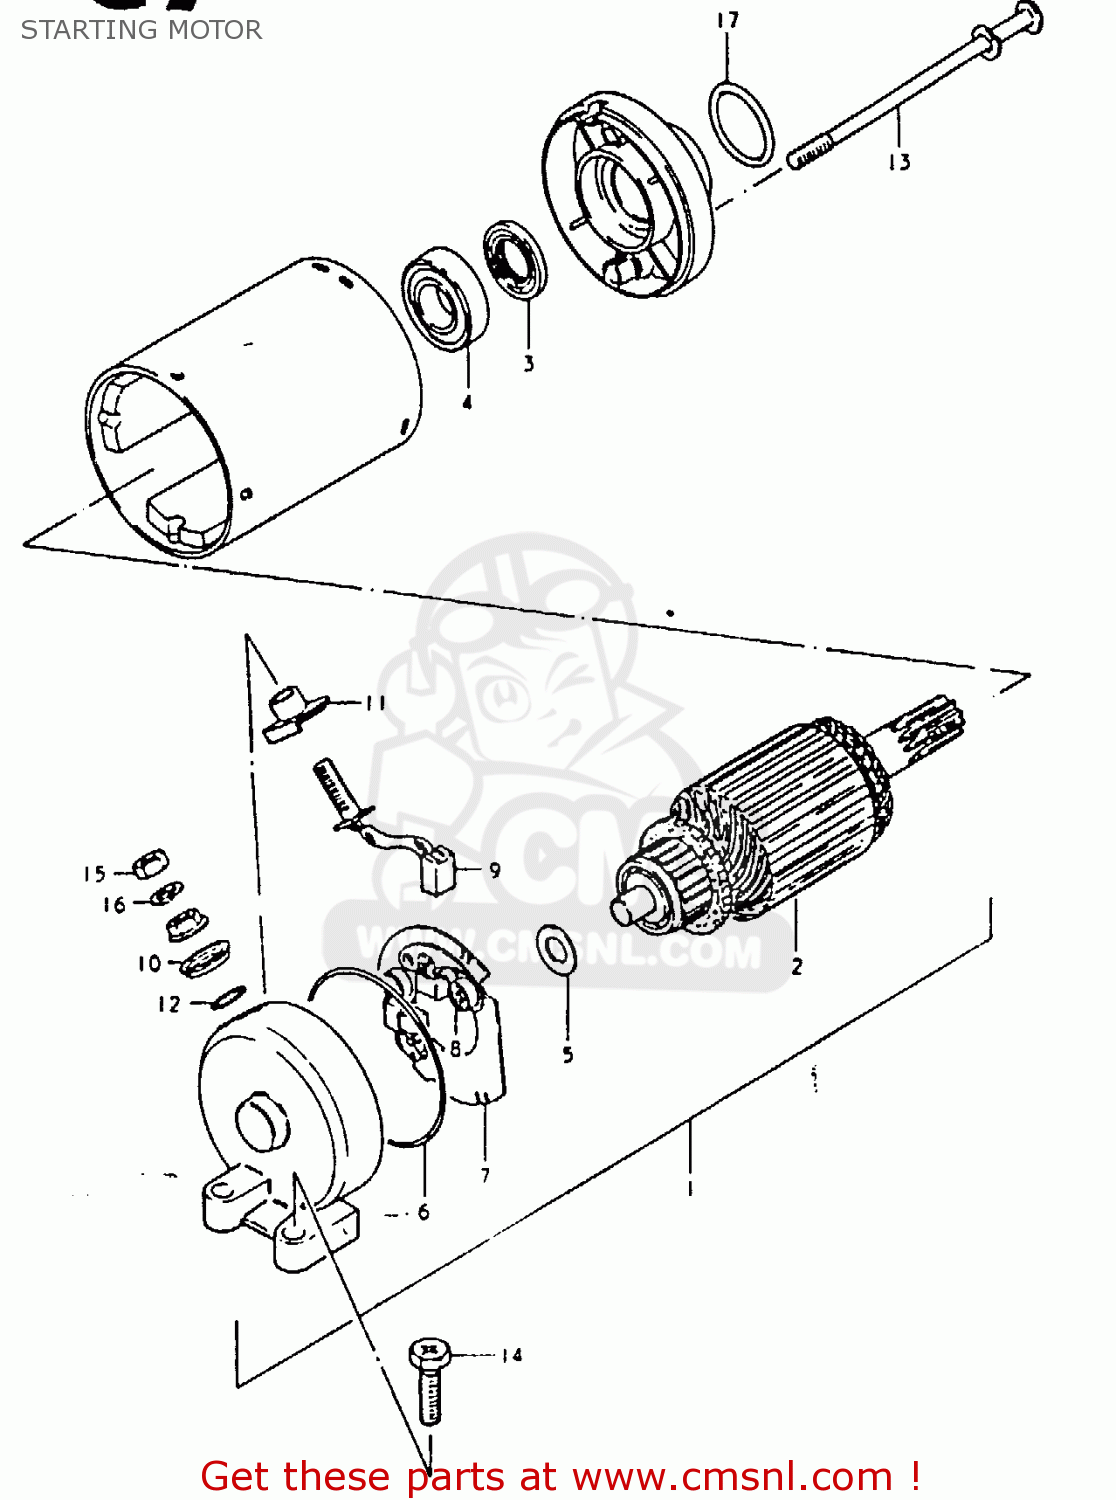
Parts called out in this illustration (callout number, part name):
1	MOTOR ASSEMBLY,STARTING
2	ARMATURE
3	SEAL,OIL
4	BEARING
5	SHIM,ARMATURE
6	O RING
7	HOLDER,BRUSH
8	SPRING
9	BRUSH (+)
10	BUSHING (1)
11	BUSH,NO.2
12	O-RING
13	BOLT,STARTING MOTOR HOUSING
14	SCREW (6X25)
15	NUT 6MM
16	LOCK WASHER
17	O RING(D:2,ID:24.5)
